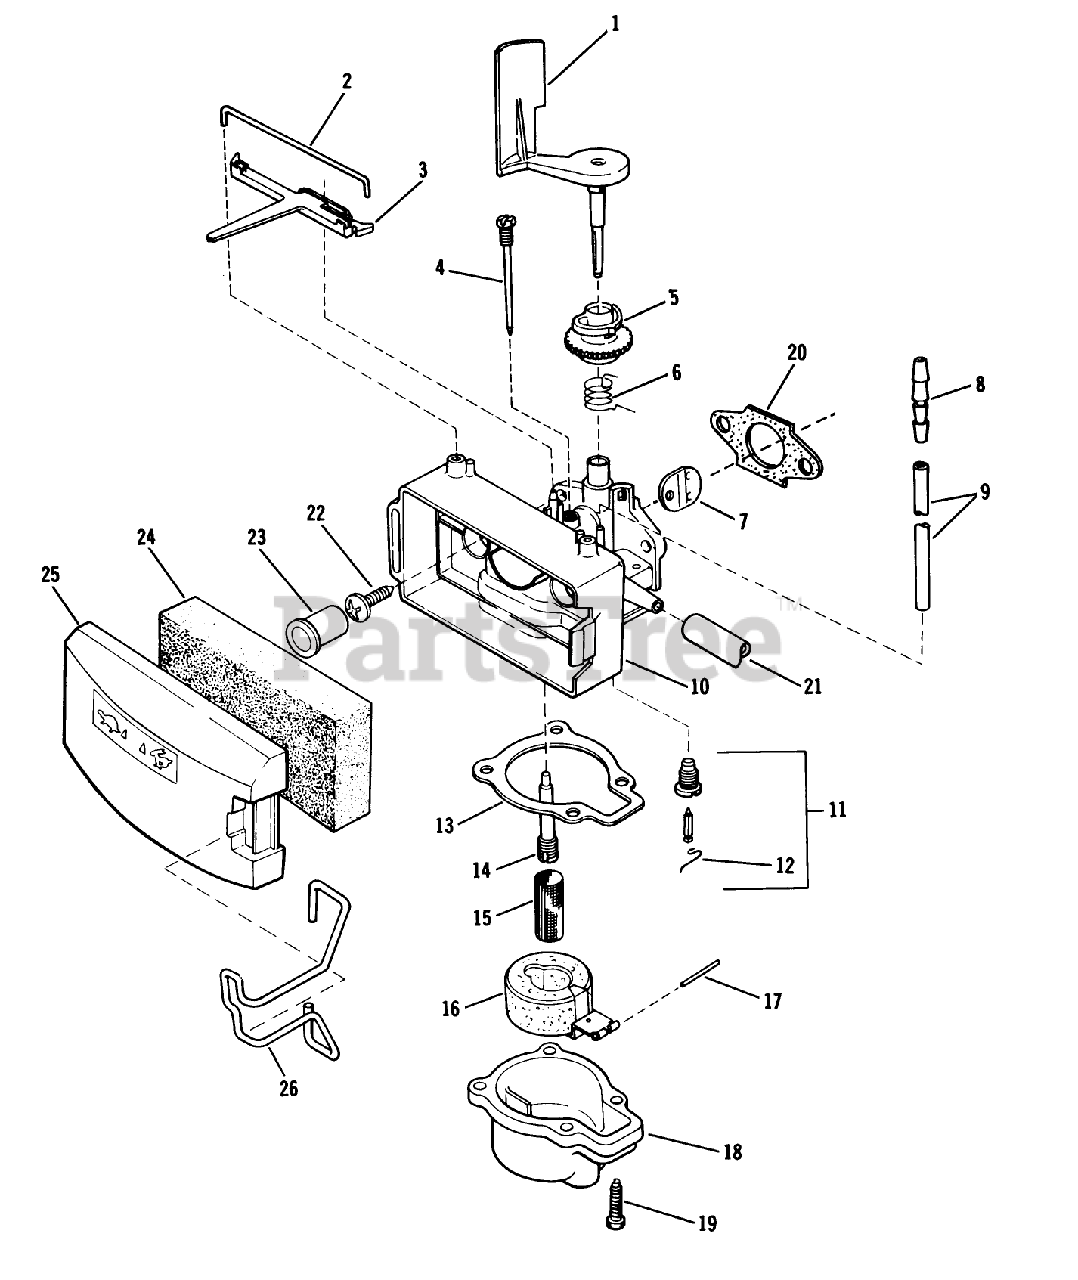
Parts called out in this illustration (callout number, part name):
2	RETAINER
3	LEVER S
4	NEEDLE ADJ. AY S
5	COLLAR-ADJUST, AIRVANE
6	SPRING,THROTTLE S
7	DISC S
8	REDUCER-CONNECTOR
9	TUBING S
10	CARB BODY S
15	FILTER-FUEL VS
19	SCREW-HH
20	GASKET CARB S
21	GAS LINE
22	SCREW
26	RETAINER-COVER, FILTER
